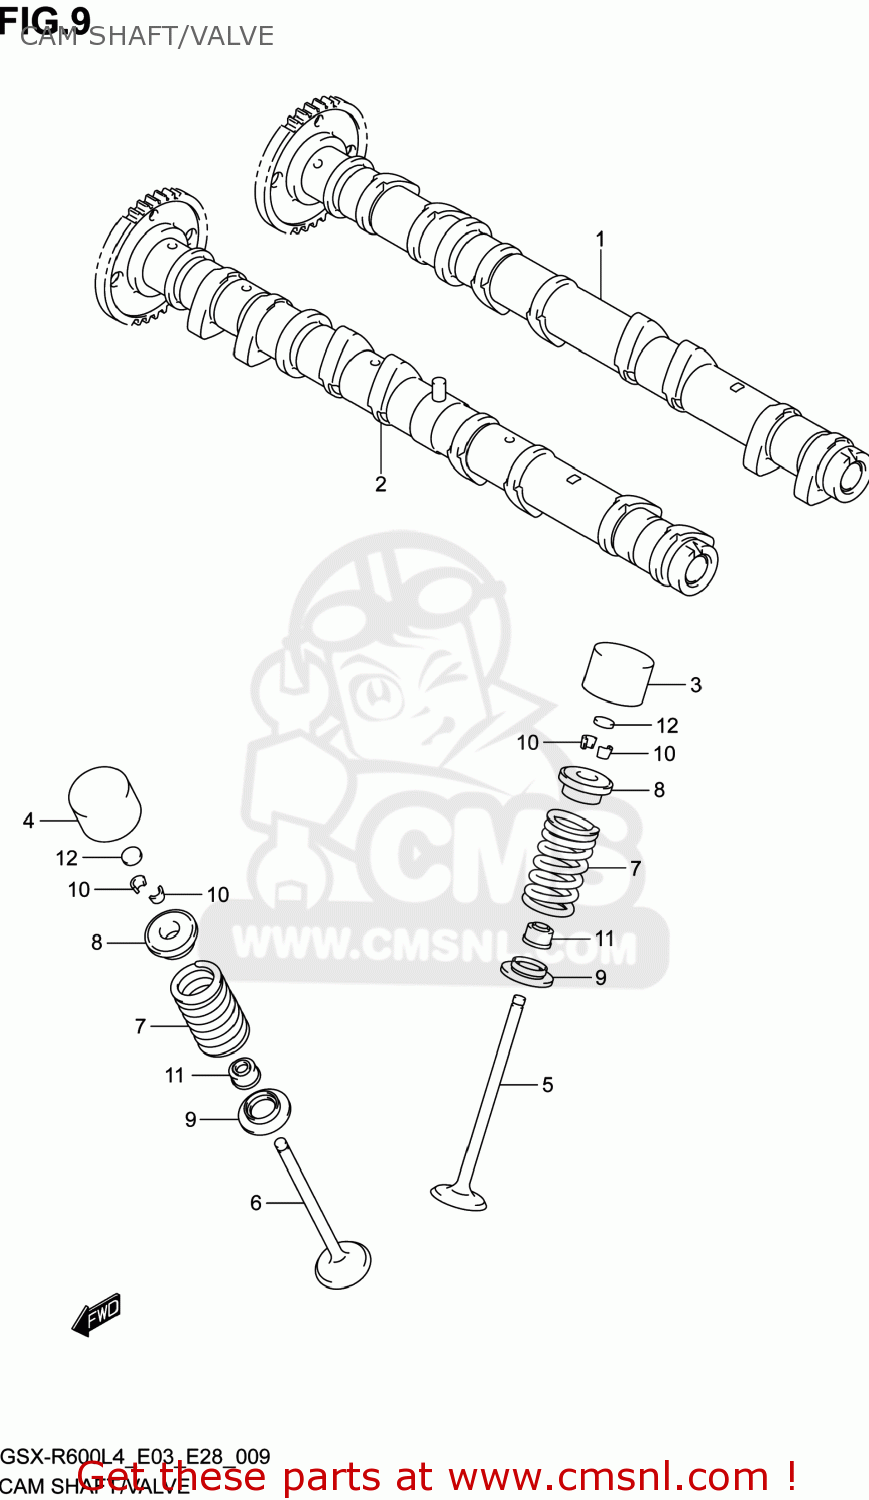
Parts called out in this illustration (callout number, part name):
1	CAMSHAFT,INTAKE
2	CAMSHAFT,EXHAUST
3	TAPPET
4	TAPPET
5	VALVE,INTAKE
6	VALVE,EXHAUST
7	SPRING,VALVE
8	RETAINER,VALVE SPRING
9	SEAT,VALVE SPRING
10	COTTER VALVE
11	SEAL,OIL(4.5X10X8)
12	SHIM,TAPPET
13	SHIM SET,TAPPET
14	CASE,TAPPET SHIM
